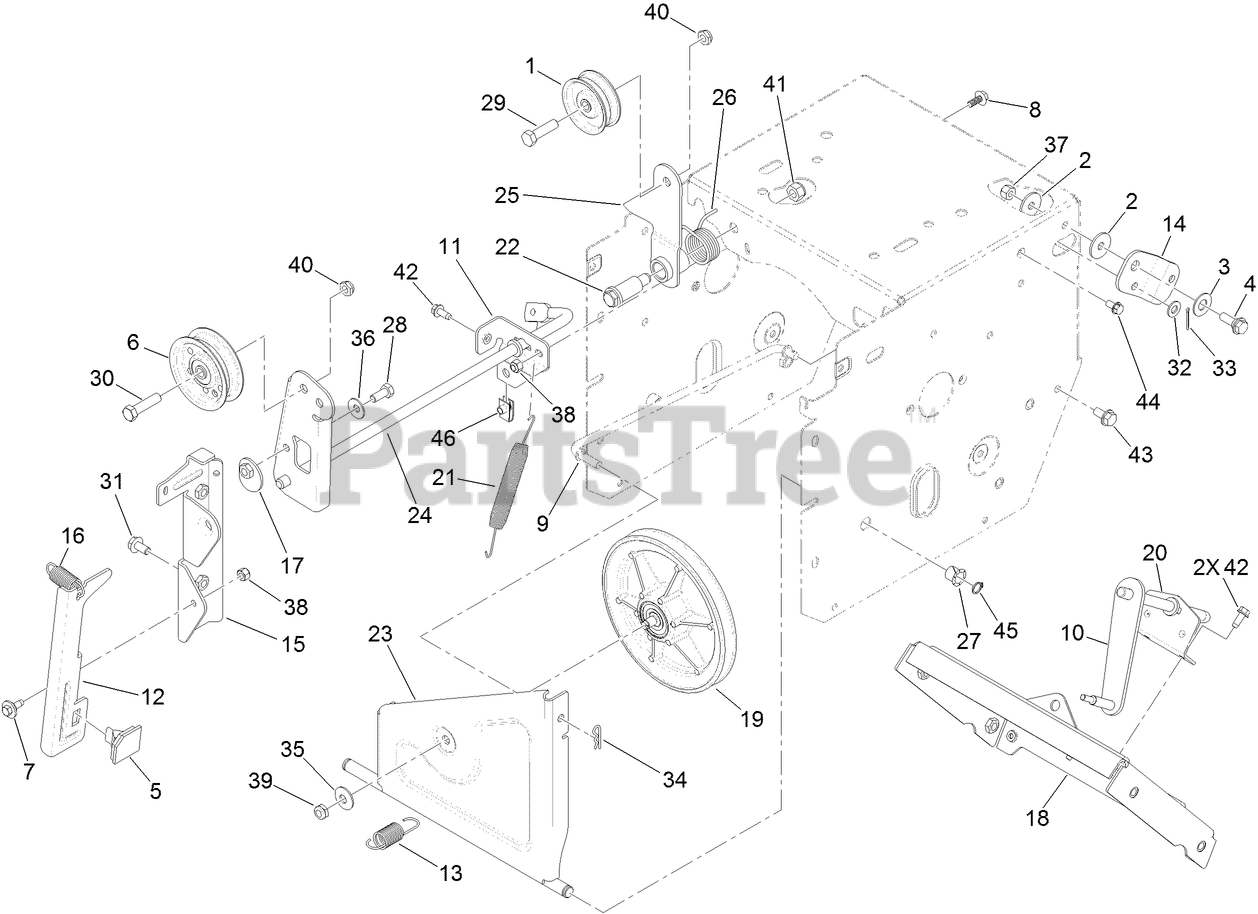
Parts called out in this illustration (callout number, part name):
1	PULLEY-IDLER
2	WASHER-PIVOT
3	WASHER
4	SCREW-SHOULDER
5	PAD-BRAKE
6	PULLEY-IDLER
7	SCREW-SHOULDER
8	SCREW-HHF
9	LINK-CONTROL, SPEED
10	LEVER-CONTROL, TRACTION
11	BRACKET-CLUTCH, IMPELLER
13	SPRING-EXTENSION
14	BELLCRANK-DRIVE
16	SPRING-EXTENSION
18	SHIFT PLATE ASM
19	PULLEY-TRACTION
20	BRACKET-ROD, SHIFT
22	BOLT-SHOULDER
23	BRACKET-WHEEL, FRICTION
24	IMPELLER CLUTCH ASM
25	TRACTION IDLER ARM
26	SPRING-TORSION
27	BUSHING-NYLINER
28	SCREW-HH
29	SCREW-HH
30	SCREW-HH
31	SCREW-HHF
32	WASHER-PLAIN
33	PIN-COTTER
35	WASHER-BELLEVILLE
36	WASHER-BELLEVILLE
37	NUT-LOCK, NI
38	NUT-LOCK, NI
39	NUT-HEX
41	NUT-LOCK, NI
42	SCREW-HWH
43	SCREW-HWHTF
44	SCREW-HWH
45	RING-RETAINING
